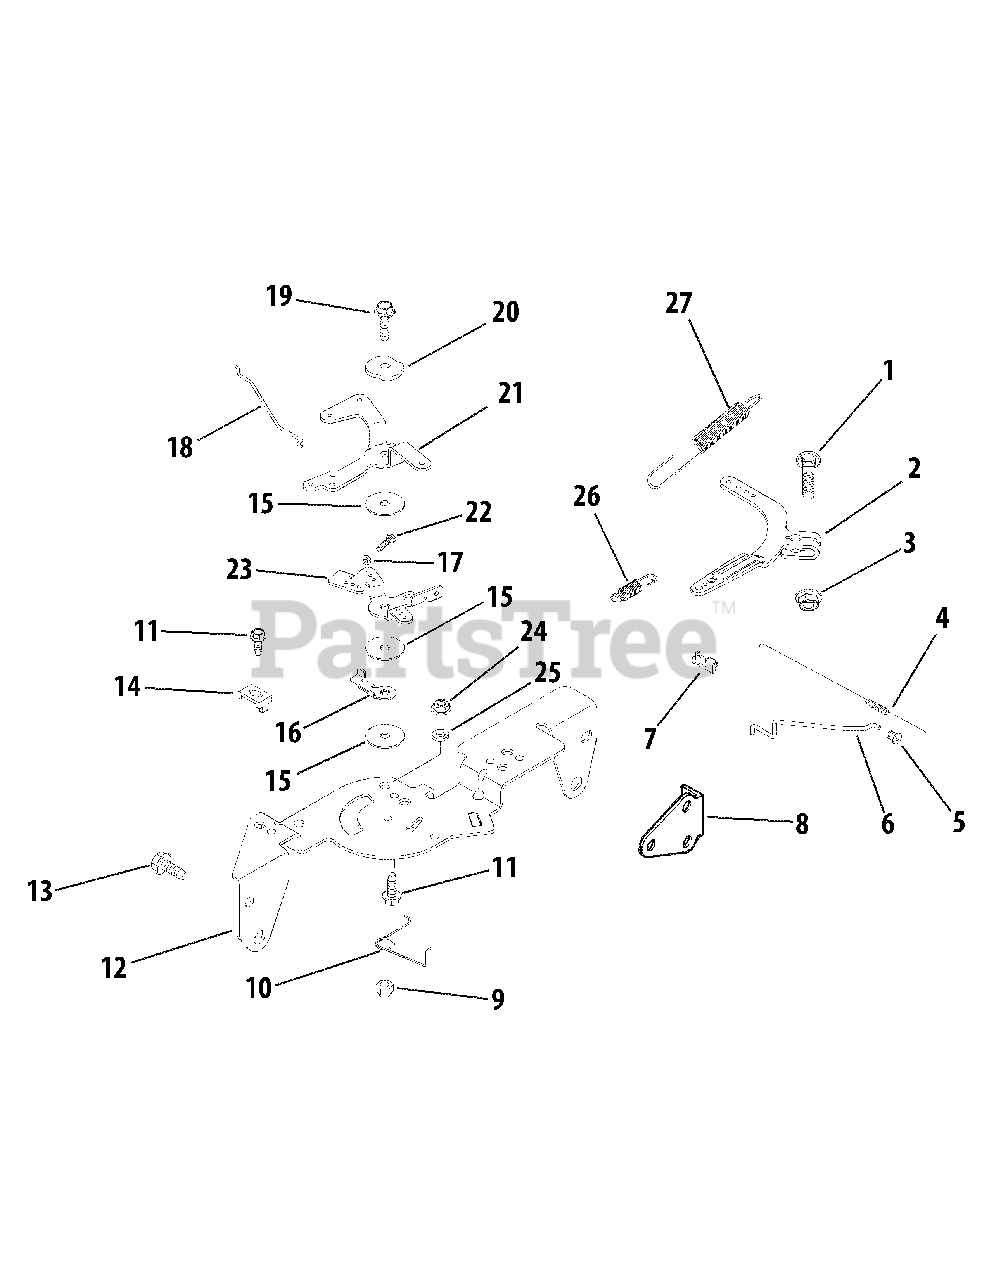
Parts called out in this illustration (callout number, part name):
1	Screw, Round Hd. Square Neck
2	Lever, Governor
3	Nut, Hex Flange M6 x 1.0
4	Spring, Linkage
5	Bushing, Linkage Retaining
6	Linkage, Throttle
7	Bushing, Linkage Retaining
8	Bracket, Support
9	Nut, Hex Lock M5 x 0.8
10	Spring, Choke Return
11	Screw, Hex Flange M5 x 0.8 x 16
12	Bracket, Control
13	Screw, Hex Flange M6 x 1.0 x 16
14	Clamp, Cable
15	Washer , Plain 5.5mm
16	Lever, Throttle Actuator
17	Nut, Hex M4 x 0.7
18	Linkage, Choke
19	Screw, Hex Flange M5 x 0,.8 x 20
20	Washer, Spring 1/4"
21	Lever, Choke
22	Screw, Hex Cap M4 x 0.7 x30
23	Lever, Throttle Control
26	Spring, Governor
27	Spring, Throttle Limiter
